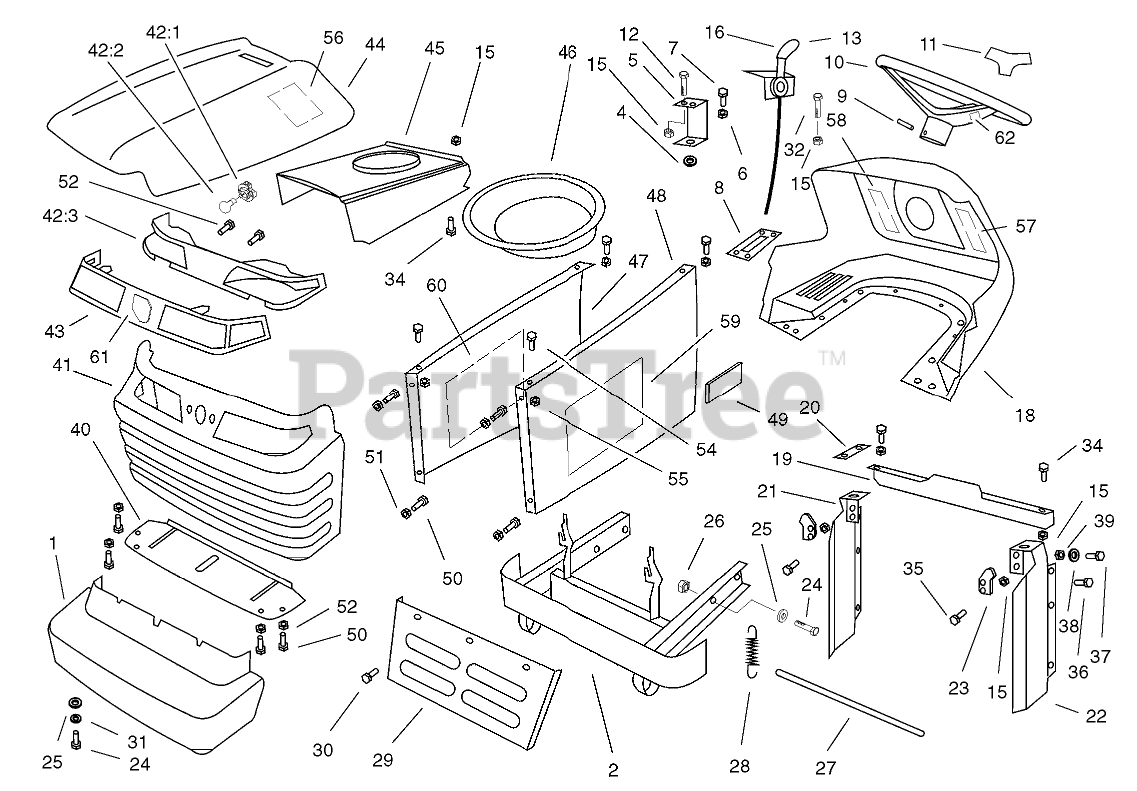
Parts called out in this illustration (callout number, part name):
1	COVER-BUMPER
2	BUMPER
4	BUSHING
5	HOLDER-TANK, FUEL
6	NUT-LOCK
9	PIN-SPIROL
10	WHEEL-STEERING 14 INCH
11	COVER-WHEEL, STEERING
12	SCREW-FLAT HEAD
15	NUT-LOCK
16	CABLE-THROTTLE and CHOKE
18	PANEL-DASH
20	BRACKET
21	PANEL-RIGHT
22	PANEL-LEFT
23	LATCH-HOOD
24	SCREW-HH
25	WASHER-PLAIN
26	NUT-LOCK, NI
27	BAR-SAFETY
28	SPRING-HOOD
29	SHIELD-HEAT
30	SCREW-TAP
31	WASHER-SPRING
32	SCREW-HEX
38	WASHER
39	NUT-HEX
40	BRACKET
42:1	SOCKET-LIGHT
42:2	BULB
42:3	REFLECTOR-LIGHT
43	LENS - HEADLIGHT
44	HOOD-TOP
45	HOOD - BAFFLE
46	PLENNUM-AIR
47	SIDE-HOOD, LH
48	SIDE-HOOD, RH
49	FOAM-SIDEPANEL
51	NUT-HEX
52	SCREW-PLASTITE
54	SCREW-HWH
56	FOAM-HOOD
57	DECAL-PTO
58	DECAL-CHOKE/THROTTLE/KEY
59	DECAL-HOOD, LH
60	DECAL-HOOD, RH
61	EMBLEM-HORSEHEAD
62	DECAL
